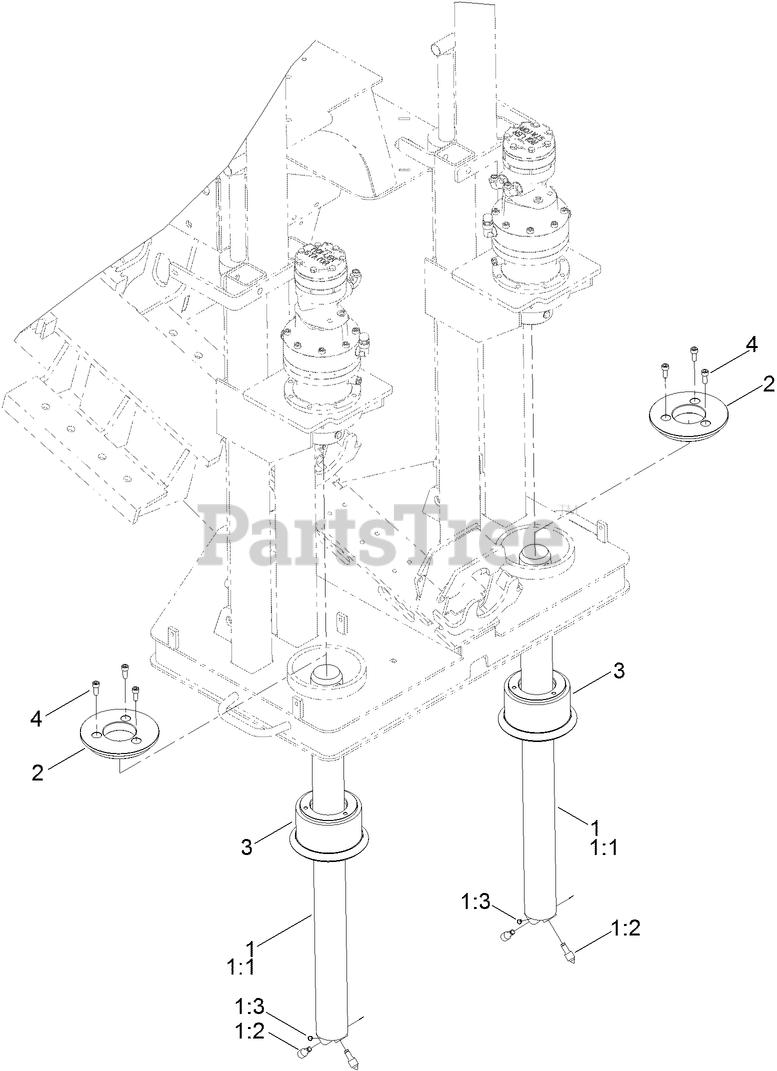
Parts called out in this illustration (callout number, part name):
1	HD ROCK STAKE ASM
1:1	STAKE-ROCK, HD
1:2	BIT-BULLET, MINI
1:3	RING-SNAP
2	RING-GUIDE,TOP
3	GUIDE-STAKE
4	SCREW-HSH
